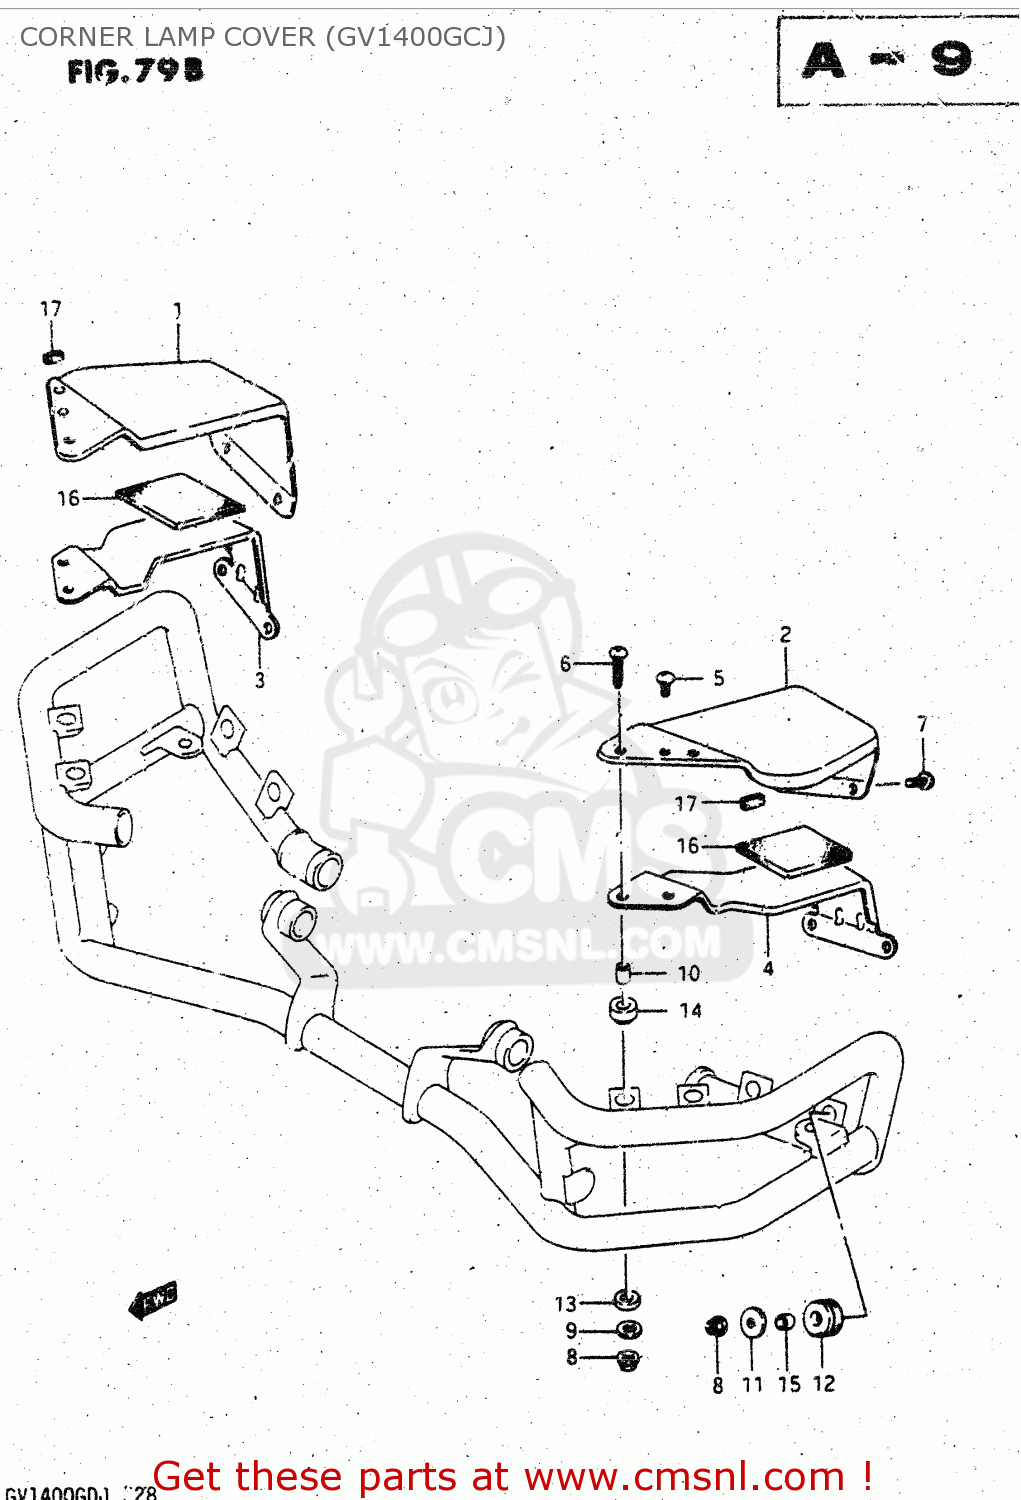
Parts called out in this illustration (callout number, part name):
1	COVER,CORNER LAMP,RIGHT
2	COVER,CORNER LAMP,LEFT
3	COVER,CORNER LAMP,LOWER
4	COVER,CORNER LAMP,LOWER
5	SCREW
6	SCREW
7	SCREW
8	NUT
9	WASHER (5.5X14X1.2)
10	SPACER
11	WASHER (5.5X20X1.2)
12	CUSHION
13	CUSHION
14	CUSHION
15	SPACER(6.1X9X7.5)
16	CUSHION,CORNER LAMP CVR CTR
17	CUSHION, SIDE
